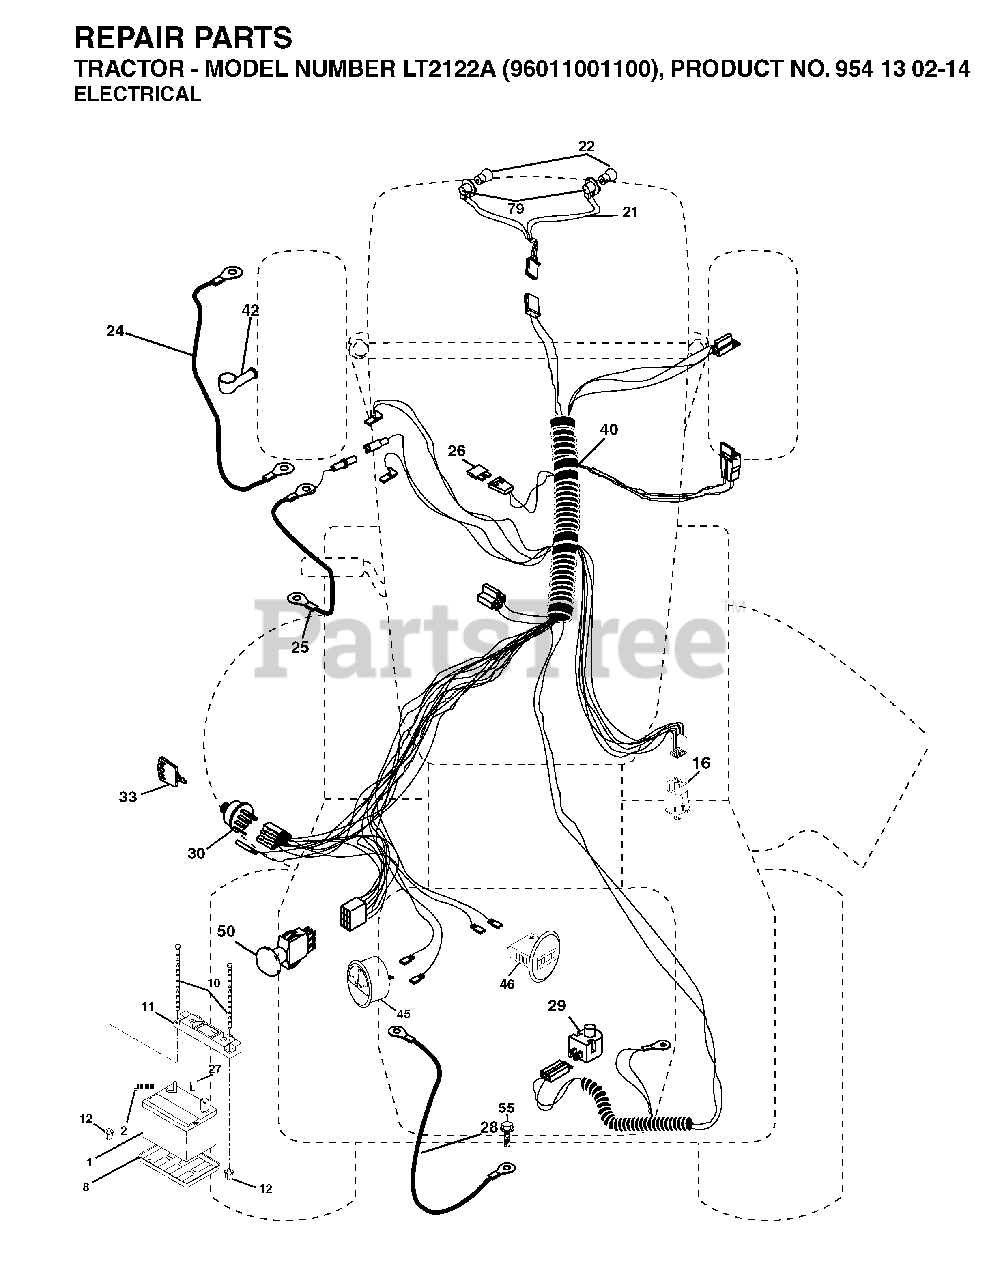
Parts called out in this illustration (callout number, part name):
1	BATTERY 12V .35 AMP
8	BATTERY TRAY T
10	BOLT 1/4-20 X 7.5
11	BATTERY HOLDDOWN
12	NUT, PUSH NYLON 1/4" BATTERY
16	SWITCH INTERLOOK PUSH-IN
21	HARNESS.W/LIGHT SOCKET
22	LIGHTBULB
26	FUSE 20AMP
27	NUT
28	CABLE GROUND 6 GA 21" 90T BLK
29	PLUNGER SWITCH (COLOR:OLIVE)
30	IGNITION SWITCH
33	KEY MLD GEN DELTA
42	COVER.TERMINAL.RED
46	HOURMETER SNAP-IN
50	PTO SWITCH
79	BULB HOLDER ASM.
